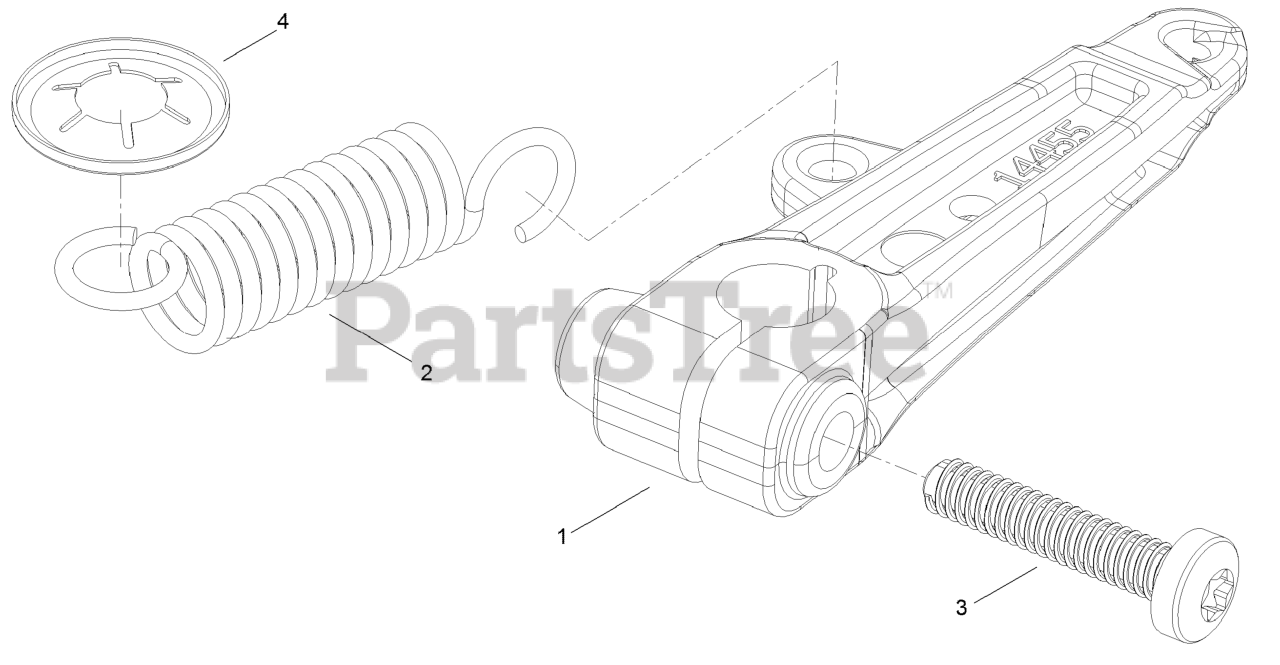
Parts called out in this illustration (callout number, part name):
1	Lever-Clutch
2	SPRING-EXTENSION
4	Washer-Lock
